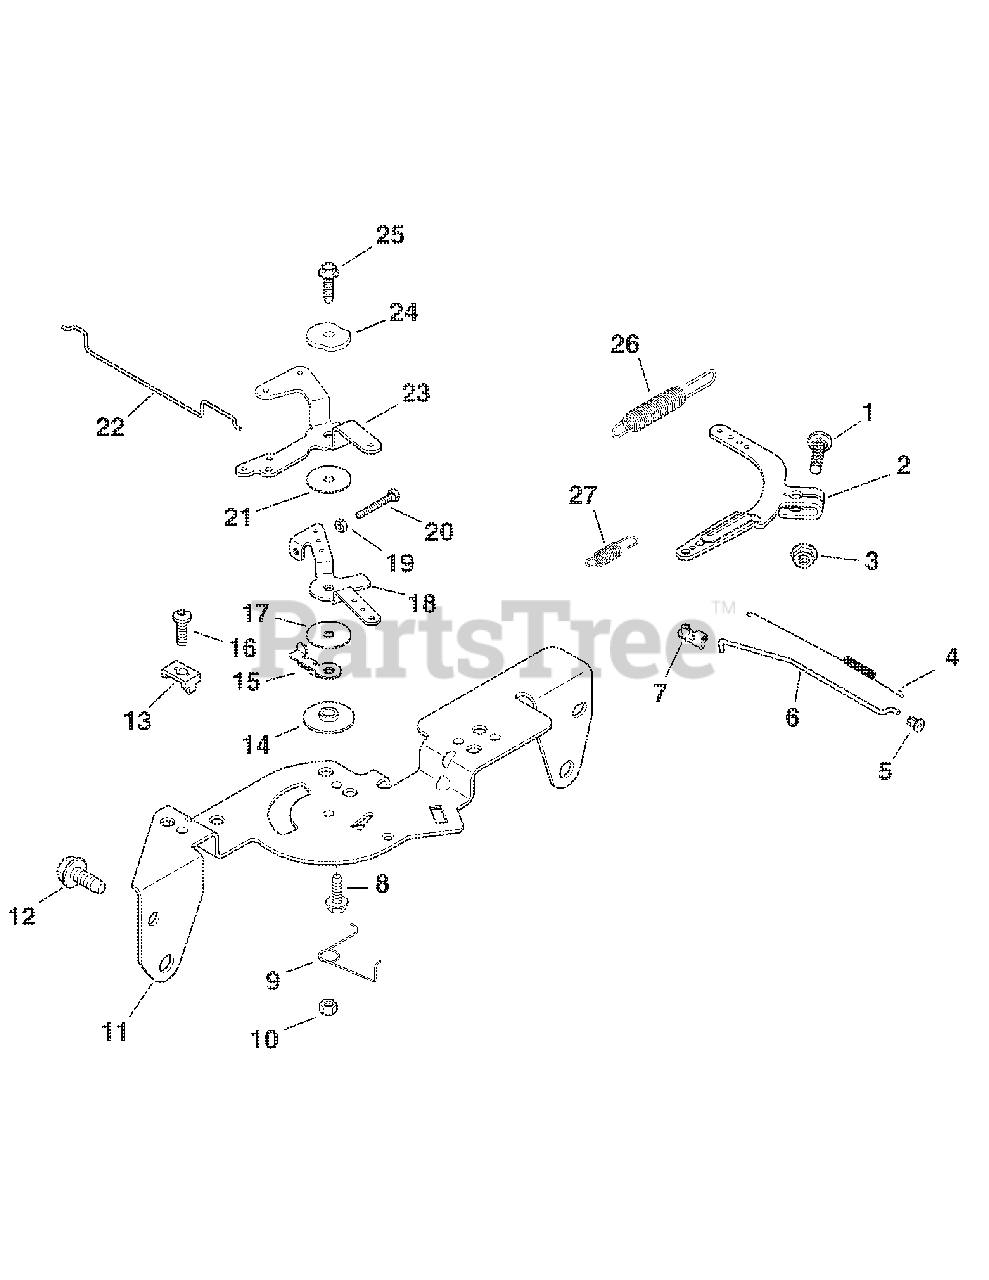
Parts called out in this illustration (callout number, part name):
1	Bolt, rd hd sq neck, M6x1.0x25
2	Lever, governor
3	Nut, flange M6x1.0
4	Spring, linkage
5	Bushing, linkage retaining
6	Linkage, throttle
7	Bushing, throttle linkage
8	Screw, hex. Flange M5 x 0.8 x 16 (2)
9	Spring, choke return
10	Nut, hex. lock M5x0.8
11	Bracket, control
12	Screw, hex. Flange M 6x 1.0 x 16 (4)
13	Clamp, cable (2)
14	Spacer, control assembly
15	Lever, throttle actuator
16	Screw, Ibd thd frm, M5 x 0.8 x 16
17	Washer, flat, 5mm
18	Lever, throttle control
20	Screw, cap M4x0.7x30
21	Washer, flat, 5.5 mm
22	Linkage, choke
23	Lever, choke
24	Washer, spring 1/4"
25	Screw, hex. flange M5x0.8x20
26	Spring, governor
27	Spring, governor
